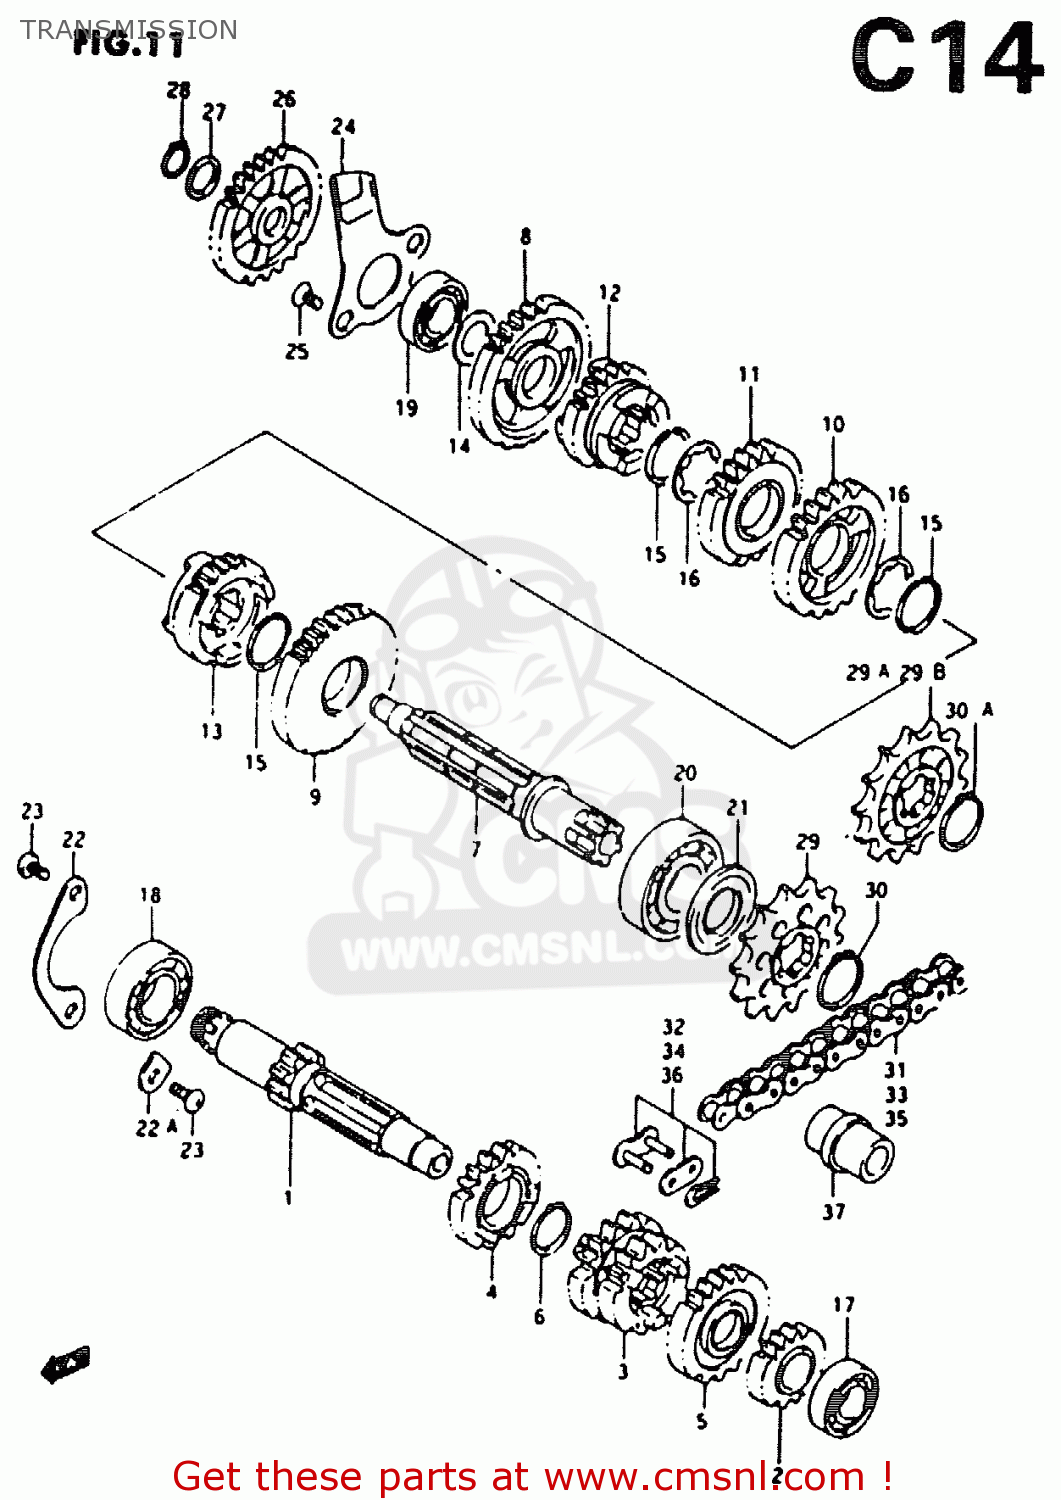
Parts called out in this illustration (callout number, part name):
1	SHAFT,COUNTER
2	GEAR,2ND DRIVE (NT:15)
3	GEAR,THIRD/FOURTH DRIVE
4	GEAR,FIFTH DRIVE
5	GEAR,6TH DRIVE
6	CIRCLIP
7	SHAFT,DRIVE
8	GEAR,FIRST DRIVEN
9	GEAR,SECOND DRIVEN
10	GEAR,THIRD DRIVEN
11	GEAR,FOURTH DRIVEN
12	GEAR,FIFTH DRIVEN
13	GEAR,SIXTH DRIVE (NT:23)
14	WASHER,THRUST
15	CIRCLIP
16	WASHER,LOCK
17	BEARING
18	BEARING(20X42X12)
19	BEARING
20	BEARING(20X47X14)
21	OIL SEAL (20X35X5)
22	RETAINER,CNTR SHAFT BEARING
22A	RETAINER
23	SCREW
24	RETAINER,DRIVESHAFT
25	SCREW
26	GEAR,KICK STARTER IDLE
27	SHIM
28	CIRCLIP,12 MM
29	SPROCKET,ENGINE
29A	SPROCKET,ENGINE(NT:14)
29B	SPROCKET,ENGINE(NT:13)
30	CIRCLIP
30A	CIRCLIP
31	CHAIN ASSEMBLY,DRIVE
32	JOINT (RK)
33	CHAIN ASSEMBLY,DRIVE
34	JOINT,CHAIN
35	CHAIN,DRIVE(428G2X118L)
36	JOINT SET,CHAIN
37	CUSHION
